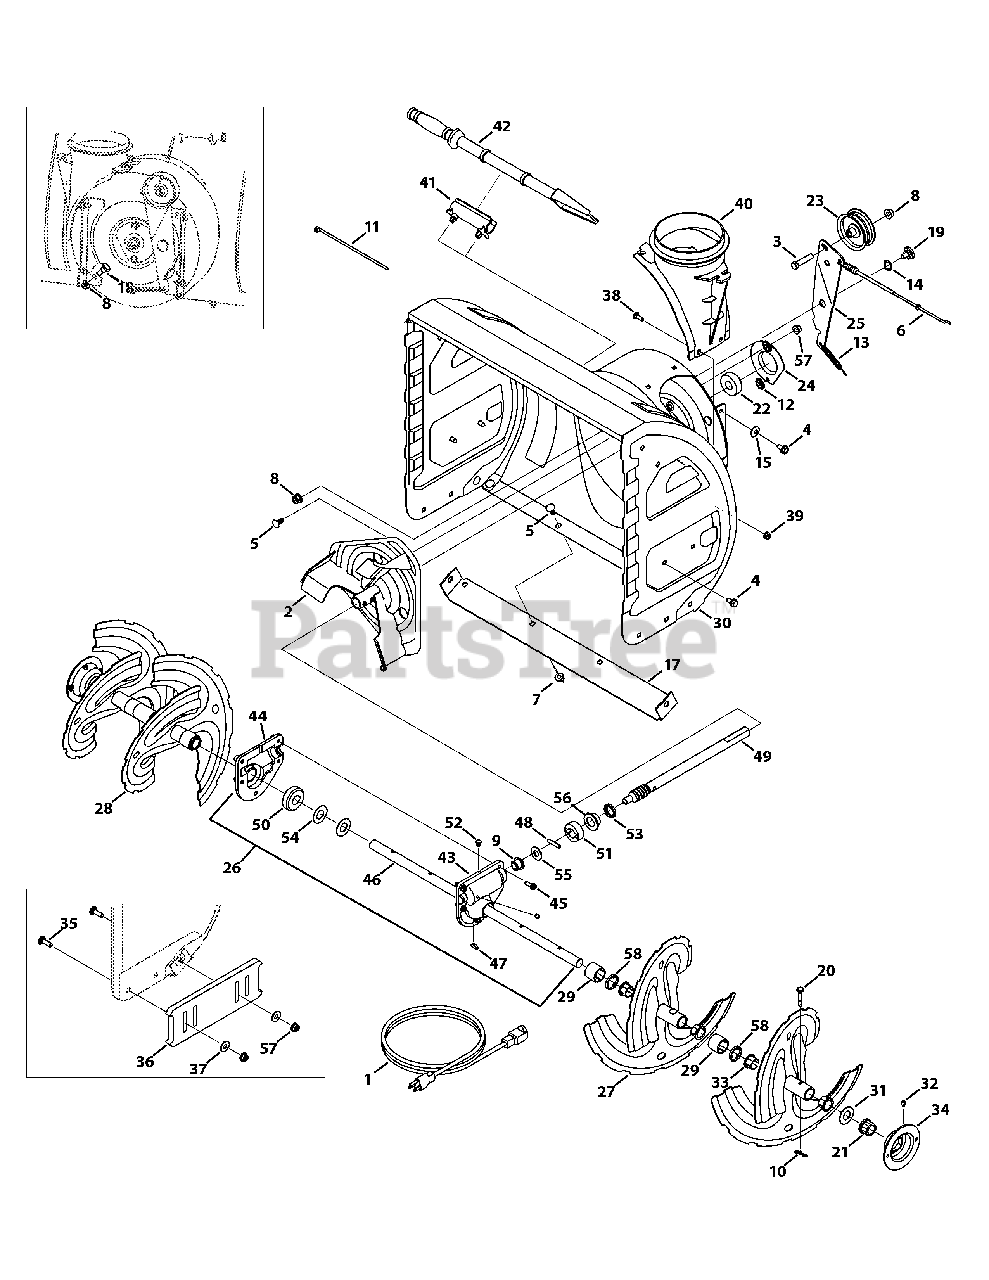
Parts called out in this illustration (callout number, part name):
1	Extension Cord
2	Impeller Assembly
3	Hex Bolt, 3/8-16 x 1.75
4	Screw, 5/16-18 x .750
5	Carriage Bolt, 5/16-18 x .750 (24", 26")
5	Carriage Bolt, 5/16-18 x .750 (28", 30") (SS)
6	Auger Clutch Cable
7	Flange Lock Nut, 5/16-18 (24", 26")
7	Hex Nut, 5/16-18 (28", 30") (SS)
8	Flange Lock Nut, 3/8-16
9	Flange Bearing, .50 x .75 x .59
10	Bow Tie Cotter Pin
11	Cable Tie
12	Push-On Nut, .25 Dia.
13	Extension Spring, .38 OD x 4.59
14	Wave Washer, .625 x .885 x .0175
15	Bell Washer, .340 x .872 x .060
17	Stainless Steel, Shave Plate, 30"
17	Stainless Steel, Shave Plate, 28"
17	Shave Plate, 26"
17	Shave Plate, 24"
18	Shoulder Screw, 3/8-16 x .496 x .336
19	Shoulder Screw, 3/8-16 x .625 x .17
21	Hex Flange Bearing
22	Flange Ball Bearing, .75 x 1.85
23	Flat Idler Pulley
24	Bearing Housing
25	Auger Idler Bracket
26	Gearbox Assembly, Auger, 30"
26	Gearbox Assembly, Auger, 28"
26	Gearbox Assembly, Auger, 26"
26	Gearbox Assembly, Auger, 24"
27	Spiral Assembly - LH
28	Spiral Assembly - RH
29	Spacer, 1.25 x .75 x 1.00
30	Auger Housing, 30"
30	Auger Housing, 28"
30	Auger Housing, 26"
30	Auger Housing, 24"
31	Flat Washer, .76 x 1.49 x .06
32	Drive Lube Fitting
33	Flange Bushing, .800 x .910
34	Bearing Housing
35	Spacer, Carriage, 5/16-18 x 1.00
36	Deluxe Slide Shoe
37	Washer, Flat, .349 x .879 x .063
38	Carriage Screw, 1/4-20 x 0.75
39	Flange Lock Nut, 1/4-20
40	Chute Adapter
41	Clean-out Tool Mtg. Bracket
42	Clean-Out Tool
43	Housing Assembly - RH
44	Housing Assembly - LH
45	Screw, 1/4-20 x 0.75
46	Axle, Auger, 30"
46	Axle, Auger, 28"
46	Axle, Auger, 26"
46	Axle, Auger, 24"
47	Hi-Pro Key
48	Dowel Pin, .25OD x 1.25
49	Worm Shaft
50	Worm Gear, 20T, 28", 30"
50	Worm Gear, 20T, 24", 26"
51	Thrust Collar
52	Plug, 1/4 x .437
53	Oil Seal, .75 x 1.131 x .188
54	Flat Washer, .76 x 1.5
55	Flat Washer, .51 x 1.12 x .06
56	Flange Bearing, .75 x 1.00 x .59
57	Flange Lock Nut
58	Spacer, 1.25 OD x .75 ID x 3/16 Lg
